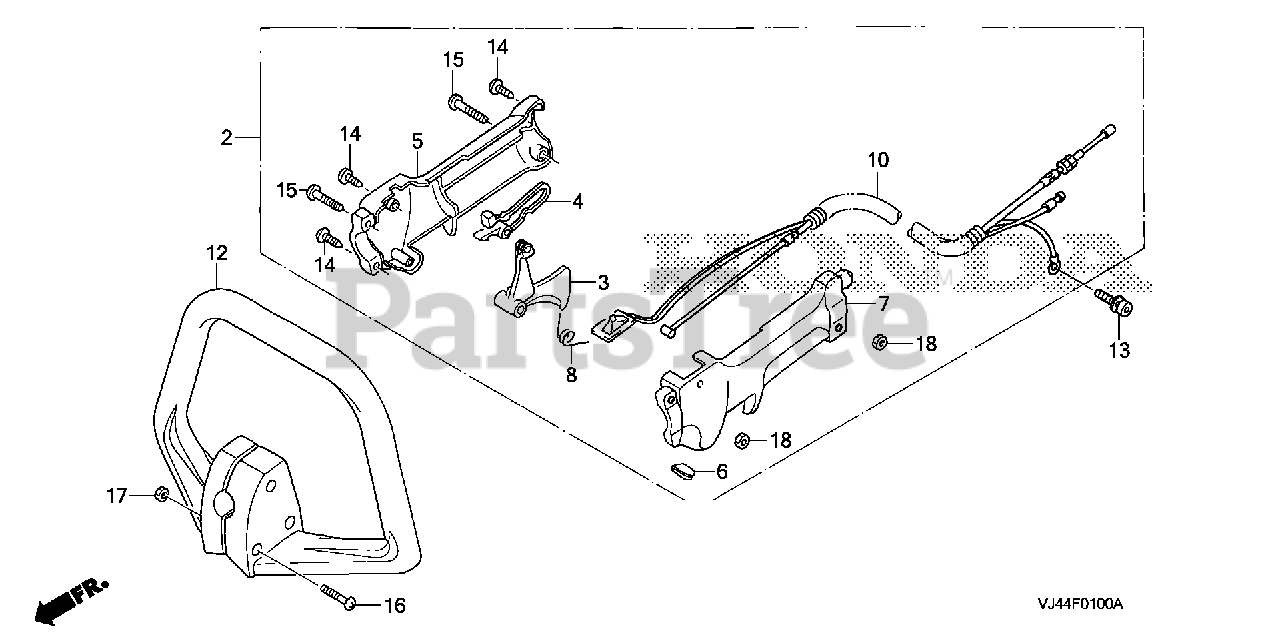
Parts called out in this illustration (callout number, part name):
2	LEVER ASSY., THROTTLE (L26) (LEVER=YELLOW)
3	LEVER, THROTTLE (YELLOW)
4	LEVER, THROTTLE LOCK (YELLOW)
5	GRIP, R. THROTTLE LEVER
6	CAP, THROTTLE LEVER
7	GRIP, L. THROTTLE LEVER
8	SPRING, THROTTLE LEVER
10	WIRE HARNESS ASSY.
12	HANDLE, LOOP
13	SCREW-WASHER (5X10)
13	SCREW-WASHER (5X12)
14	SCREW, TAPPING (4X20)
15	SCREW, PAN (5X20)
16	SCREW, PAN (5X28)
17	NUT, HEX. (5MM)
18	NUT, HEX. (5MM)
